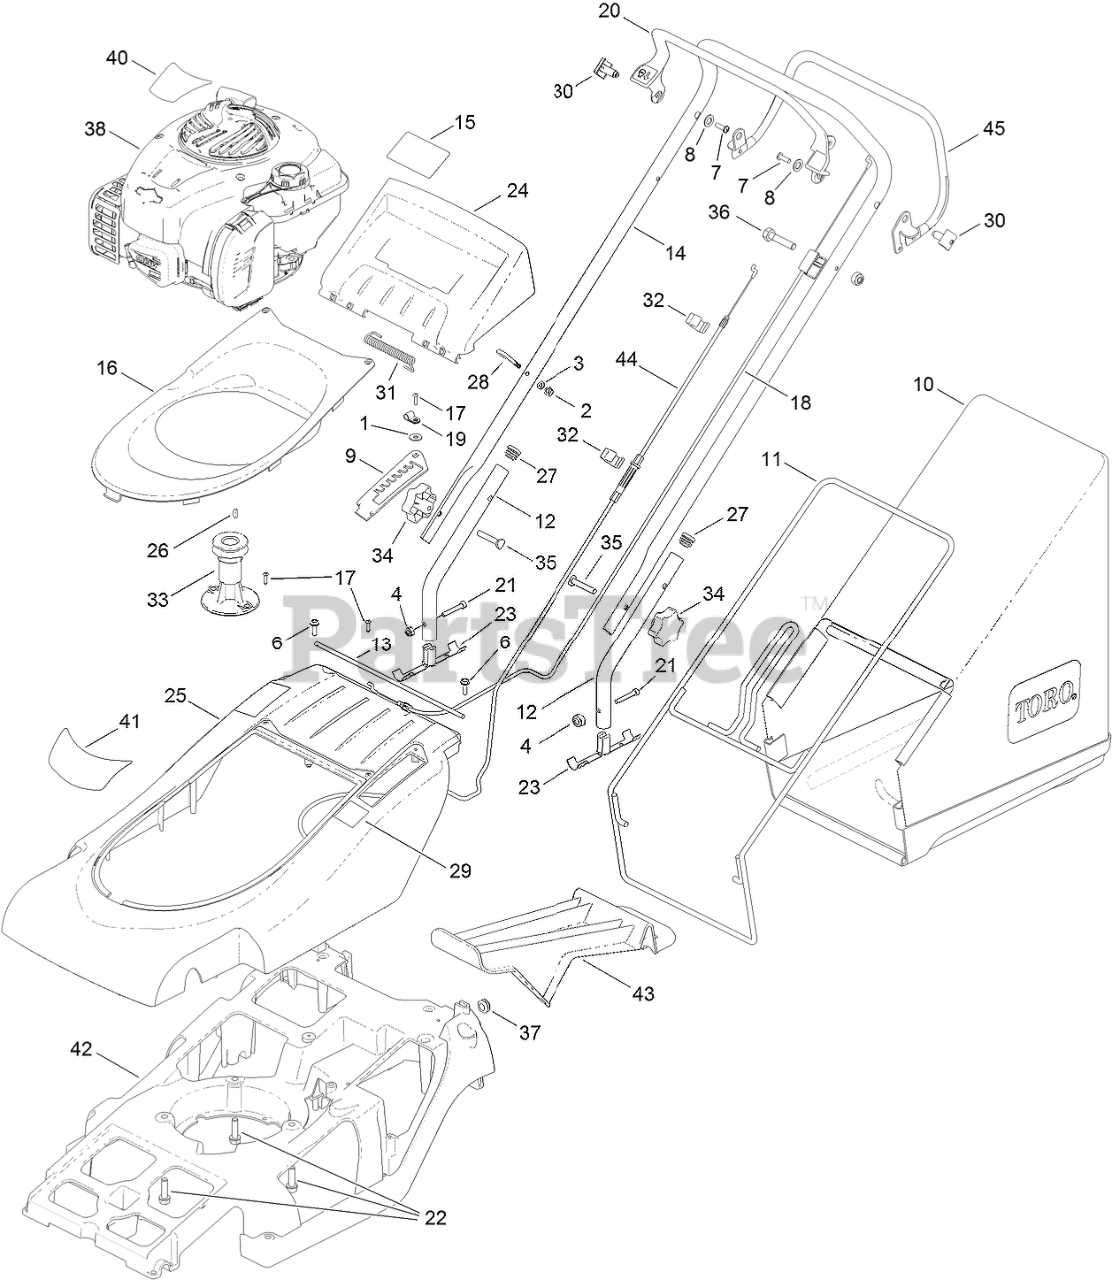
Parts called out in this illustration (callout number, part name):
1	WASHER
2	NUT-NYLOC
3	WASHER-PLAIN
4	NUT-NYLOC
6	SCREW-TAPTITE
7	SCREW
8	WASHER-NYLON
9	PLATE-HOC
10	GRASSBAG
11	FRAME-GRASSBAG
12	HANDLEBARS-LOWER
13	BAR-HINGE
14	HANDLEBARS
15	DECAL-SAFETY
16	MOULDING-TRIM
18	CABLE-BRAKE, ENGINE
19	CLIP-P
20	BAILARM
21	SCREW-SOCKET
22	SCREW-TAPTITE
23	PLUG-HANDLEBAR
24	MOULDING-DEFLECTOR, REAR
25	TOP-COVER
26	KEY-WOODRUFF
27	PLUG-TUBE
28	GUIDE-ROPE
29	DECAL-HOC
30	PIN-PIVOT
31	SPRING-DEFLECTOR
32	GUIDE-CABLE
33	CARRIER-BLADE
34	KNOB-HANDLEBAR
35	BOLT-HANDLEBAR
36	SCREW-HH
37	GROMMET-RUBBER
40	DECAL-ENGINE
41	DECAL-RECYCLE
42	CHASSIS
43	PLUG-MULCHING
44	CABLE-CLUTCH, AUTO-DRIVE
45	LEVER-CLUTCH
